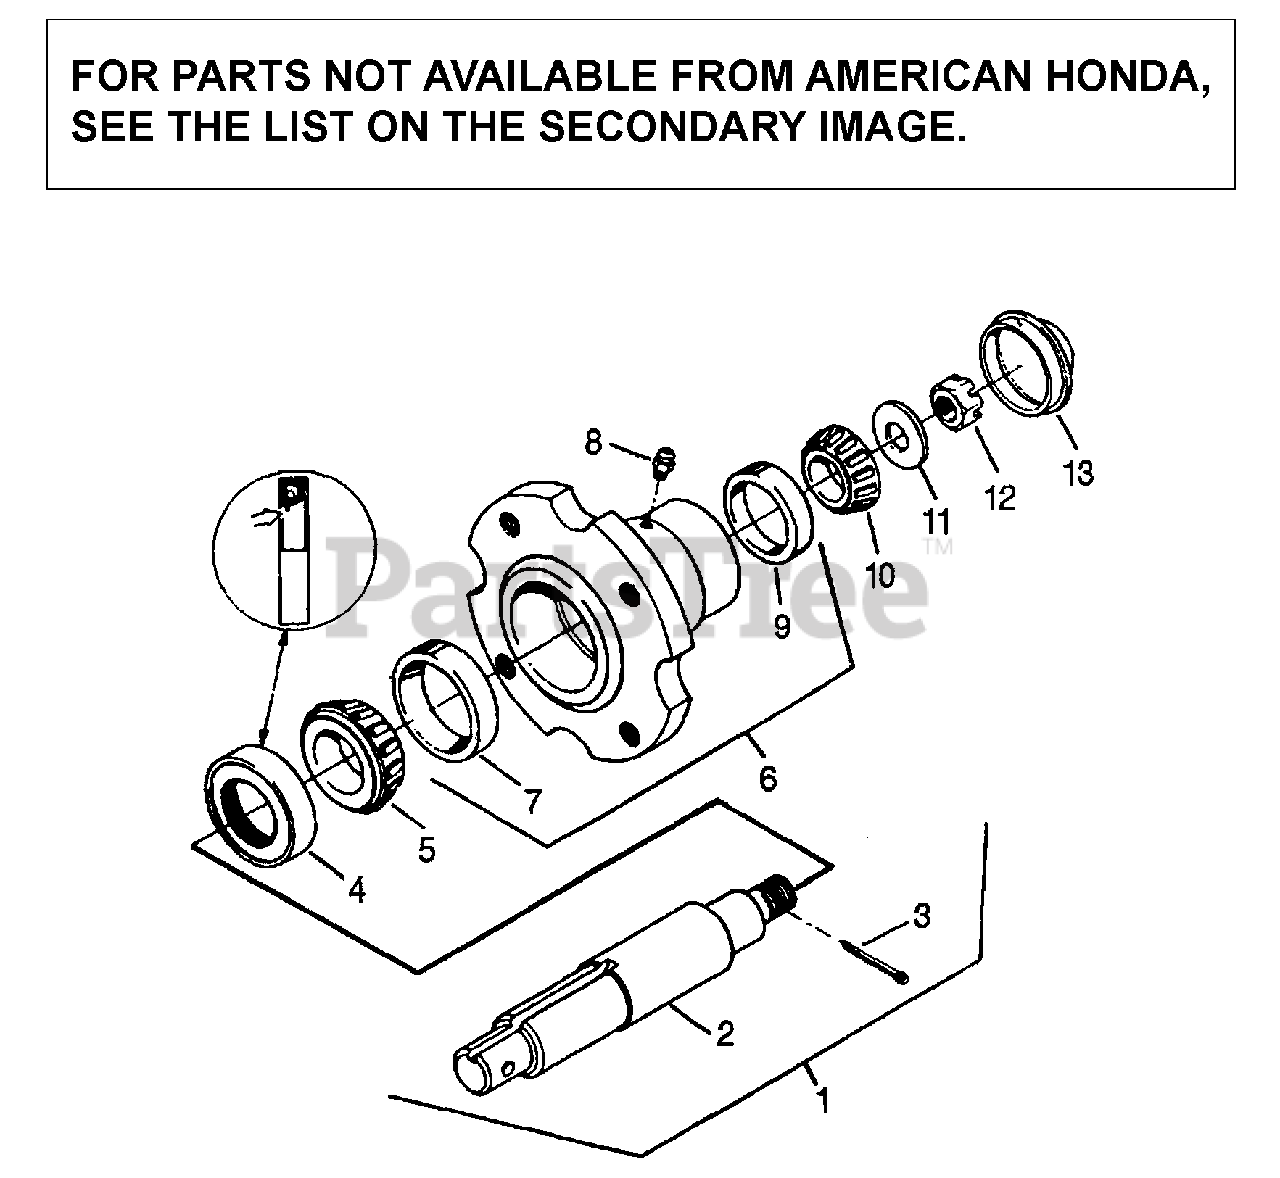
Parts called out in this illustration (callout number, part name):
1	SPINDLE ASSY., DRIVE
2	SHAFT, DRIVE SPINDLE
5	CONE, BEARING
7	CUP, BEARING
9	CUP, BEARING
10	CONE, BEARING
12	NUT, SLOTTED HEX.
13	CAP, HUB
